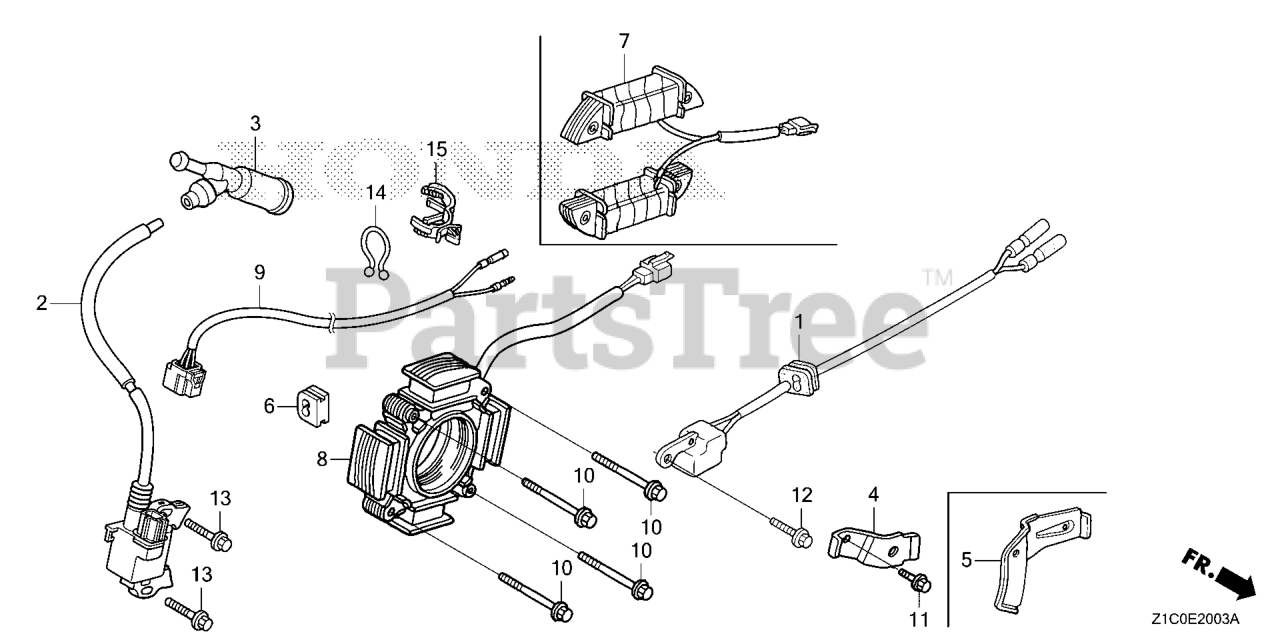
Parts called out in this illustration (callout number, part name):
2	COIL ASSY., IGNITION
2	COIL ASSY., IGNITION (IIDA)
3	CAP ASSY., NOISE SUPPRESSOR (NGK Y-EZD)
4	CLAMP, WIRE
6	GROMMET, WIRE
8	COIL ASSY., CHARGE (12V-17A)
9	WIRE HARNESS ASSY., ENGINE (SEL)
10	BOLT, FLANGE (6X40)
11	BOLT, FLANGE (6X12) (CT200)
13	BOLT, FLANGE (6X28) (CT200) Use up to Engine SN 1530314.
